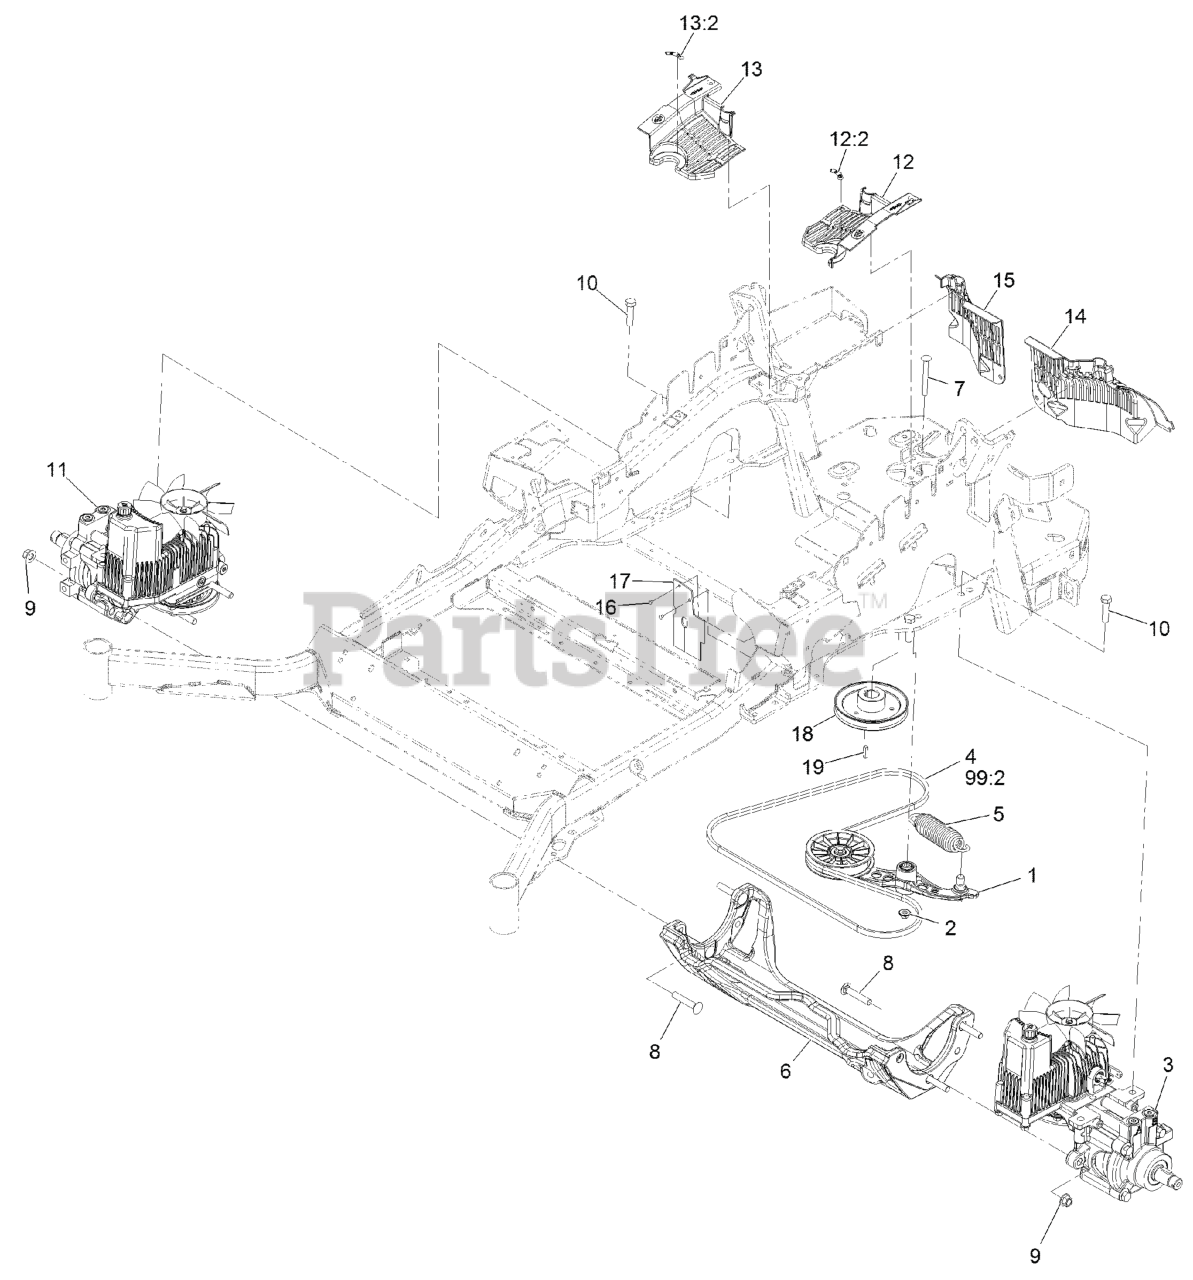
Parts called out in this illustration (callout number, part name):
1	PUMP IDLER ASM
2	Nut-Nyloc 3/8-16 Flg
3	LH HYDRO ASM (16CC W/ SHO
5	SPRING-EXTENSION
6	CRADLE-HYDRO
7	BOLT-SHOULDER, CARRIAGE 3/8-16 X 3 1/2
8	SCREW-CARR
9	Nut-Lock 1/2-13
10	SCREW-HH
11	RH HYDRO ASM (16CC W/ SHO
12	LH HYDRO GUARD ASM
12:2	DECAL-OIL, HYDRO
13	RH HYDRO GUARD ASM
13:2	DECAL-OIL, HYDRO
14	GUARD-HYDRO, REAR (LH)
15	GUARD-HYDRO, REAR (RH)
16	RIVET-POP
17	DEFLECTOR-AIR FLOW
18	SHEAVE
99:3	FILTER-HYDRO
